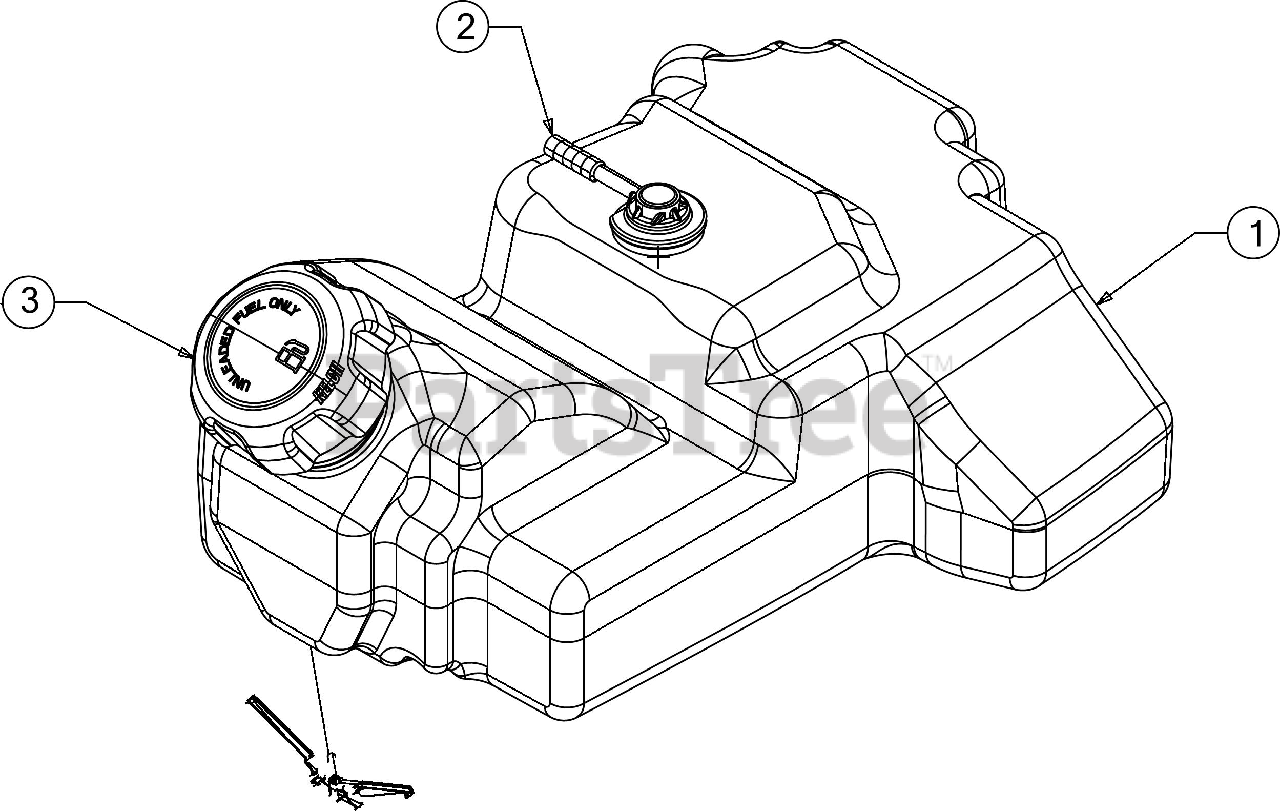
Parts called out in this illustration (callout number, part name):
1	FUEL TANK ASSEMBLY
2	VENT HOSE 3/16 ID
3	FUEL CAP W/TETHER
